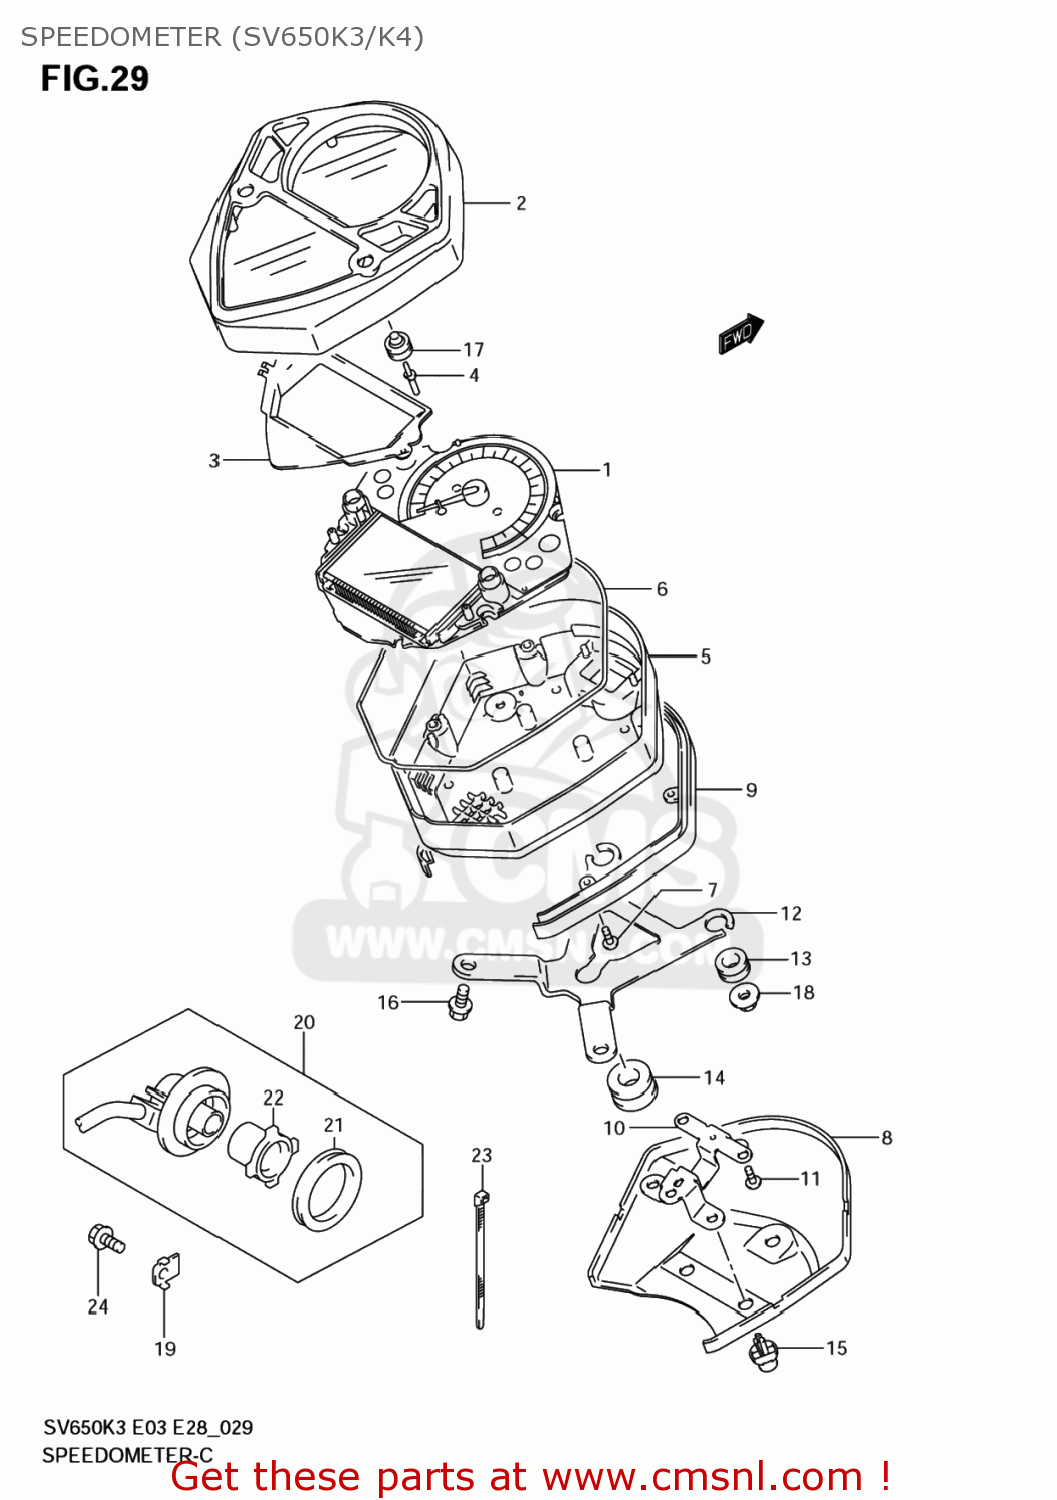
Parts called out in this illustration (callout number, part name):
1	SPEEDOMETER
2	CASE,SPEEDOMETER UPR
3	PLATE,SPEEDOMETER
4	KNOB,SPEEDOMETER
5	CASE,SPEEDOMETER LWR
6	GASKET,METER CASE (NAS)
7	SCREW,SPEEDOMETER
8	COVER,SPEEDOMETER LWR
9	DECORATION PLATE,METER CASE
10	HOLDER,SPEEDOMETER
11	SCREW(4X14)
12	BRACKET,SPEEDOMETER CASE
13	CUSHION,METER
14	CUSHION
15	CLIP
16	BOLT MAGNETO S
17	COVER,SPEEDOMETER KNOB
18	NUT
19	GUIDE,SENSOR LEAD
20	SENSOR,SPEED
21	SEAL,OIL(44X55X6)
22	ROTOR,SPEEDOMETER
23	CLAMP(L:145)
24	BOLT
